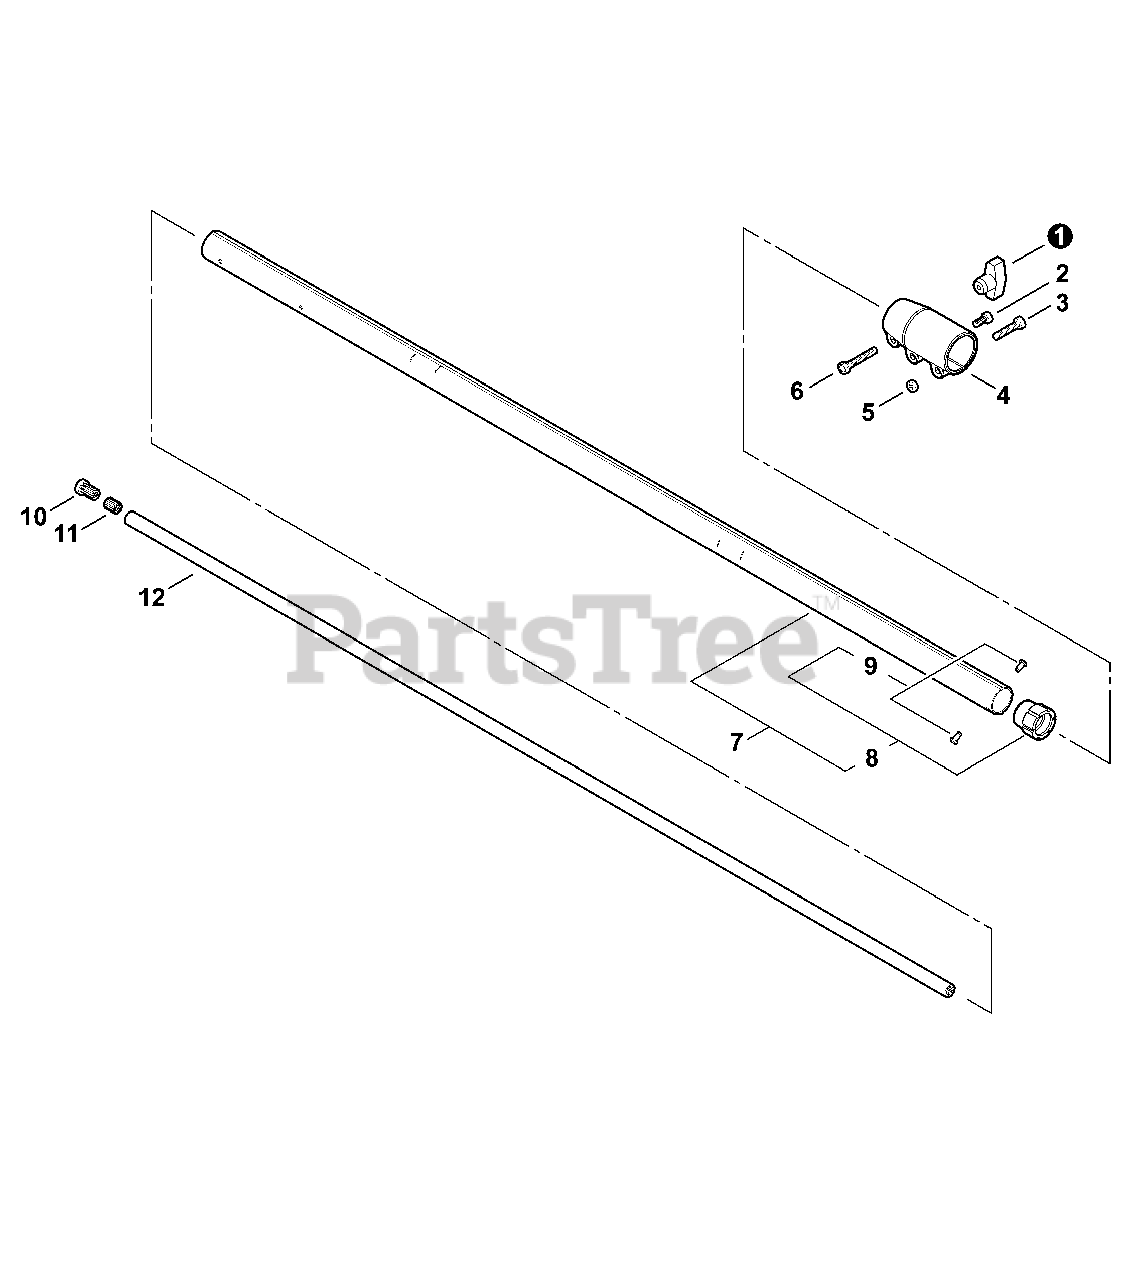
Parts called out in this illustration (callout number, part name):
1	THUMBSCREW
2	BOLT - 5×12
3	SCREW - 5×20
4	COUPLING
6	BOLT - 6×25
7	MAIN PIPE ASY - BLACK
8	BEARING HOLDER ASY
10	SOCKET - OUTER
11	SOCKET - INNER
12	DRIVESHAFT - UPPER
